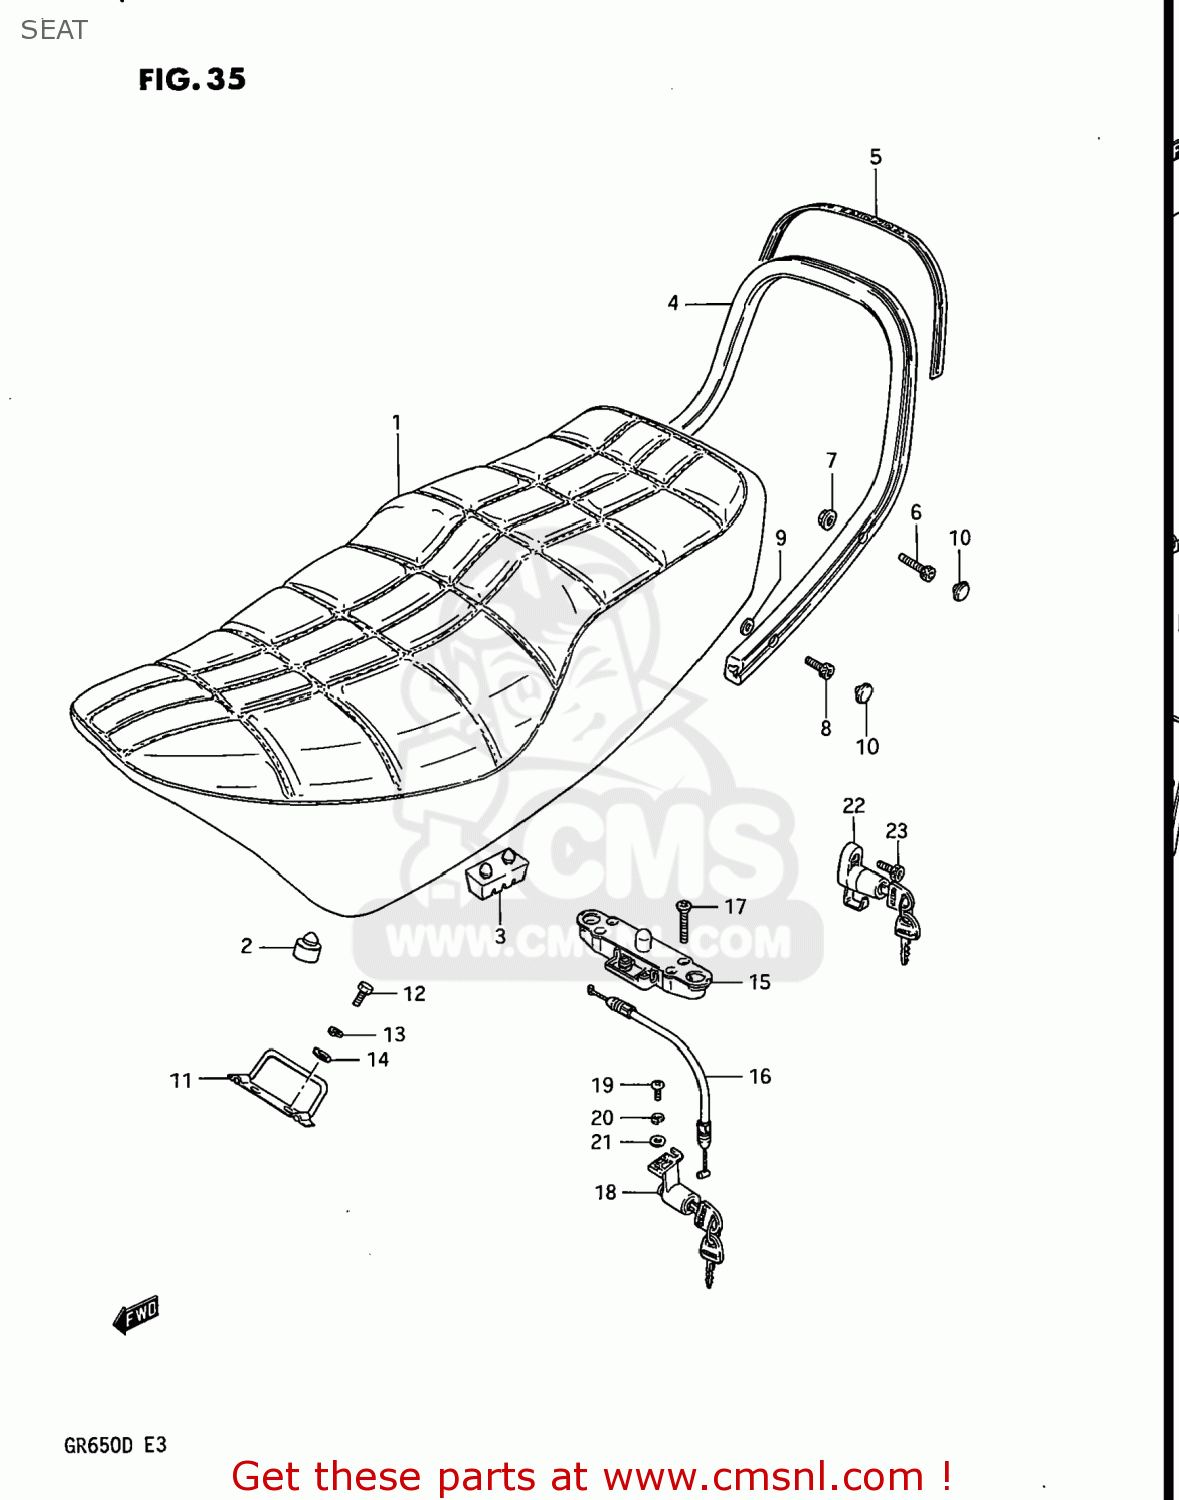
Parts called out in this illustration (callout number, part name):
1	SEAT ASSEMBLY
2	CUSHION
3	CUSHION
4	HANDLE,PILLION RIDER
5	RUBBER,PILLION RIDER HANDLE
6	BOLT
7	NUT 8MM
8	BOLT
9	WASHER
10	CAP(OD:14.5)
11	PLATE,SEAT HOOK,FRONT
12	BOLT
13	LOCK WASHER
14	WASHER
15	LOCK ASSEMBLY,SEAT STRIKER
16	CABLE,SEAT LOCK
17	SCREW
18	LOCK ASSEMBLY,SEAT
19	SCREW
20	LOCK WASHER
21	WASHER
22	LOCK SET
23	BOLT
